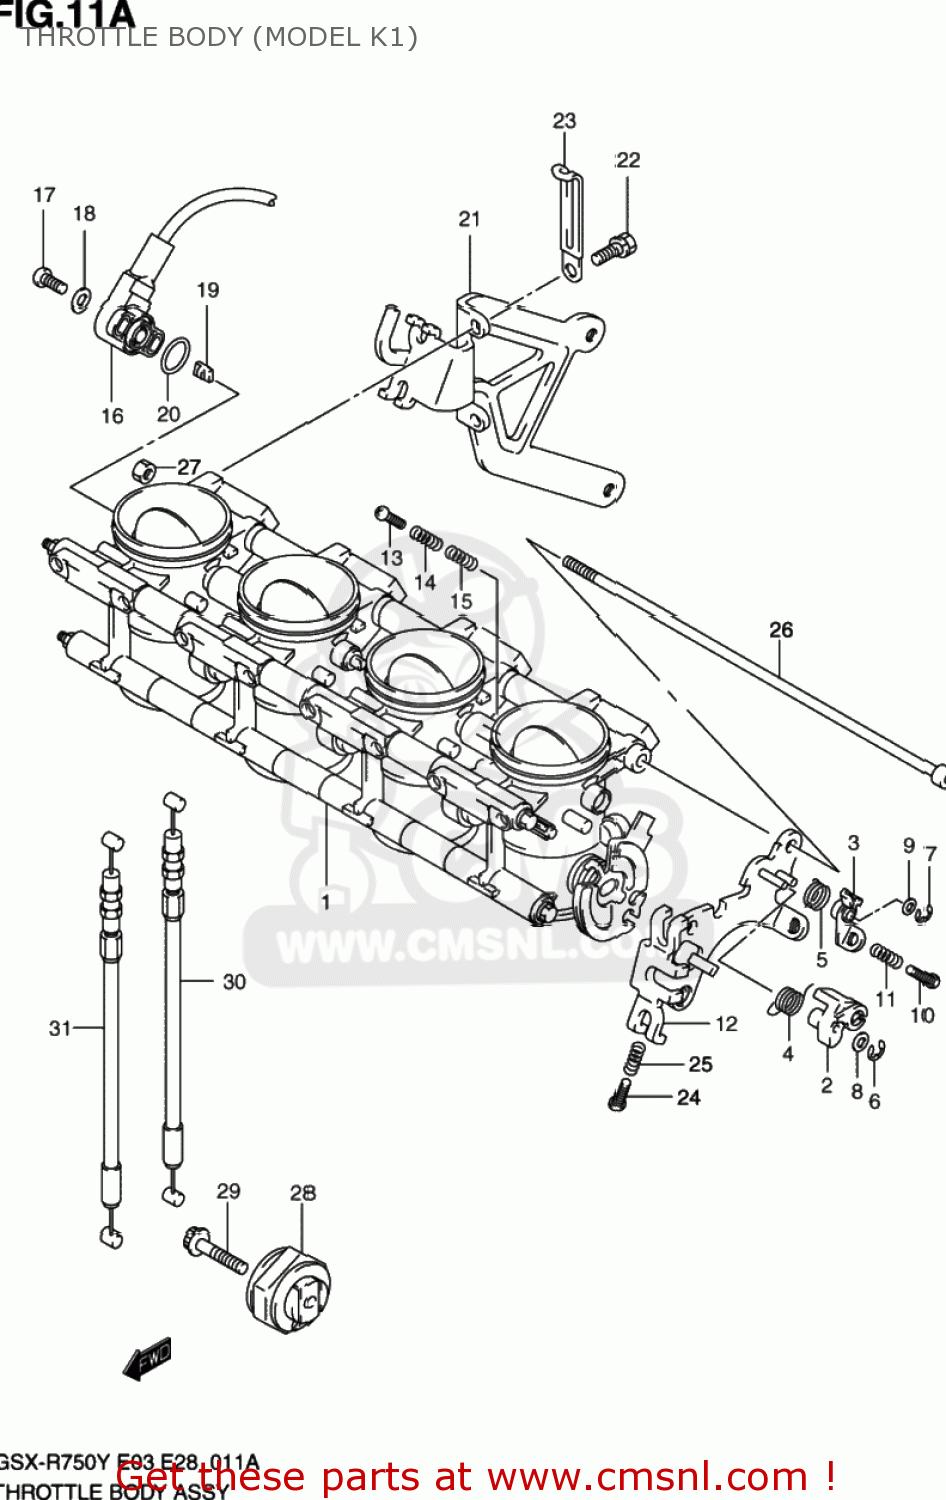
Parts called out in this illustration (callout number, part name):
1	BODY SET,THROTTLE
2	LEVER,LINK
3	LINK,LEVER
4	SPRING
5	SPRING
6	E CLIP
7	E CLIP
8	WASHER
9	WASHER
10	SCREW,STOP
11	SPRING
12	PLATE,STAY
13	SCREW,STOP
14	SPRING
15	SPRING
16	SENSOR ASSY,THROTTLE
17	SCREW
18	WASHER
19	COLLAR
20	O RING
21	PLATE,STAY
22	BOLT
23	CLAMP
24	SCREW,STOP
25	SPRING
26	BOLT
27	NUT
28	PULLEY,CONTROLLER
29	BOLT
30	CABLE,THROTTLE ACTUATOR OPEN
31	CABLE,THROTTLE ACTUATOR CLOSE
